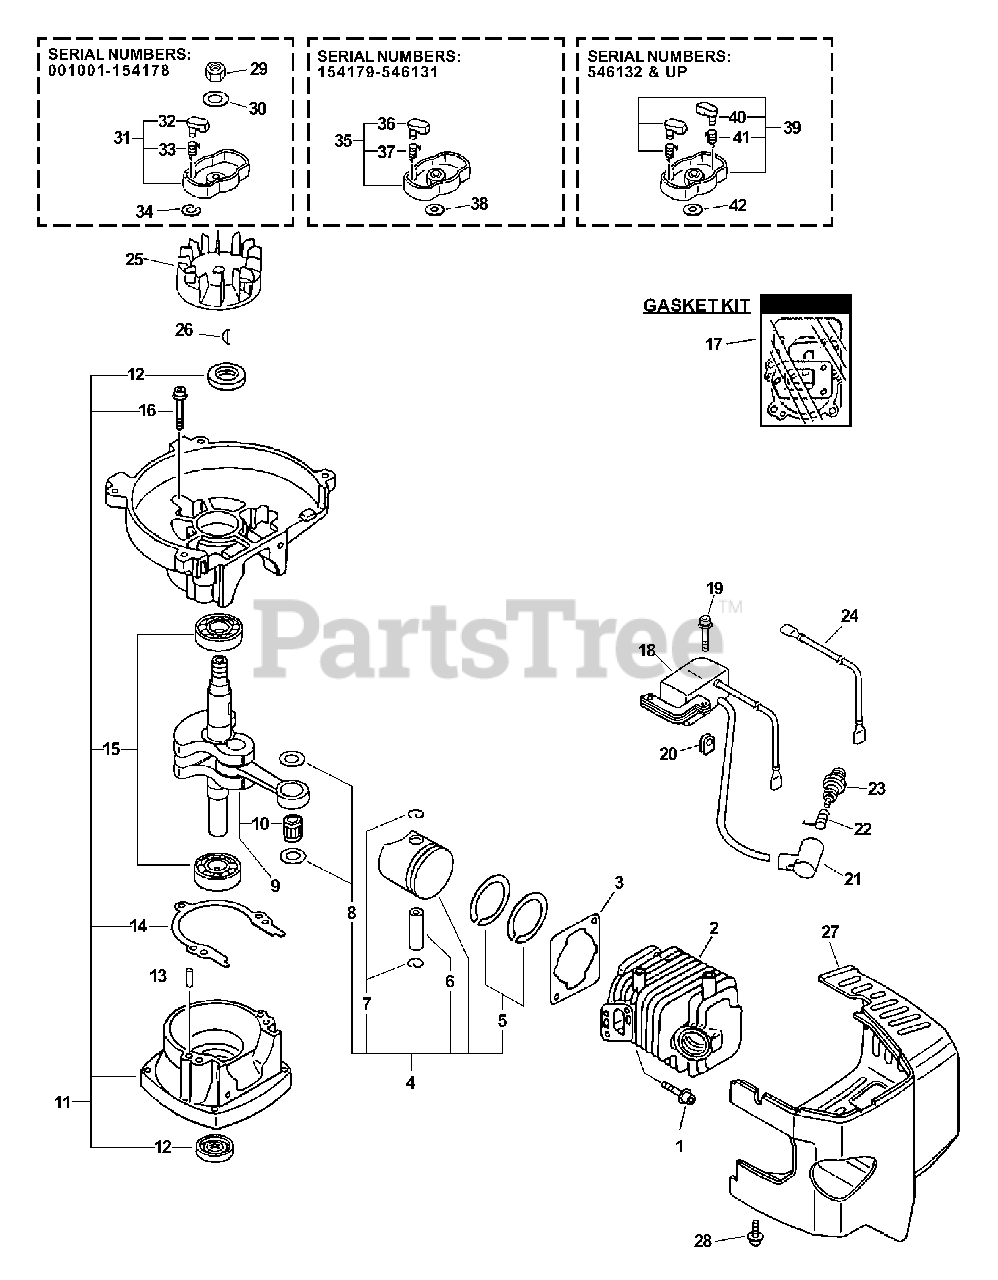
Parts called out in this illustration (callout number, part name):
1	SCREW - 5X22
2	CYLINDER
3	GASKET, CYLINDER
4	PISTON KIT
5	RING, PISTON
6	PIN, PISTON
7	RING, RETAINING
8	SPACER, PISTON
9	CRANKSHAFT ASSY
10	BEARING, NEEDLE - 8
11	CRANKCASE KIT
12	SEAL, OIL
13	PIN - LOCATING
14	GASKET, CRANKCASE
15	BEARING, BALL - 6201
16	SCREW - 5X28
17	GASKET KIT
18	COIL, IGNITION
19	SCREW - 4X22
21	CAP, SPARK PLUG
22	TERMINAL, SPARK PLUG CAP
23	SPARK PLUG -- BPMR-7A
24	LEAD - IGNITION
25	FLYWHEEL
27	COVER, ENGINE
28	SCREW - 4X18
30	WASHER - 8
31	STARTER PAWL ASSY
32	PAWL, STARTER
33	SPRING, RETURN
34	RING, RETAINING - 4
35	STARTER PAWL ASSY
36	PAWL, STARTER - BLACK
37	SPRING, RETURN
38	LOCKWASHER - 8
39	STARTER PAWL ASSY
40	SPRING, RETURN
41	PAWL, STARTER - BLACK
42	LOCKWASHER - 8
